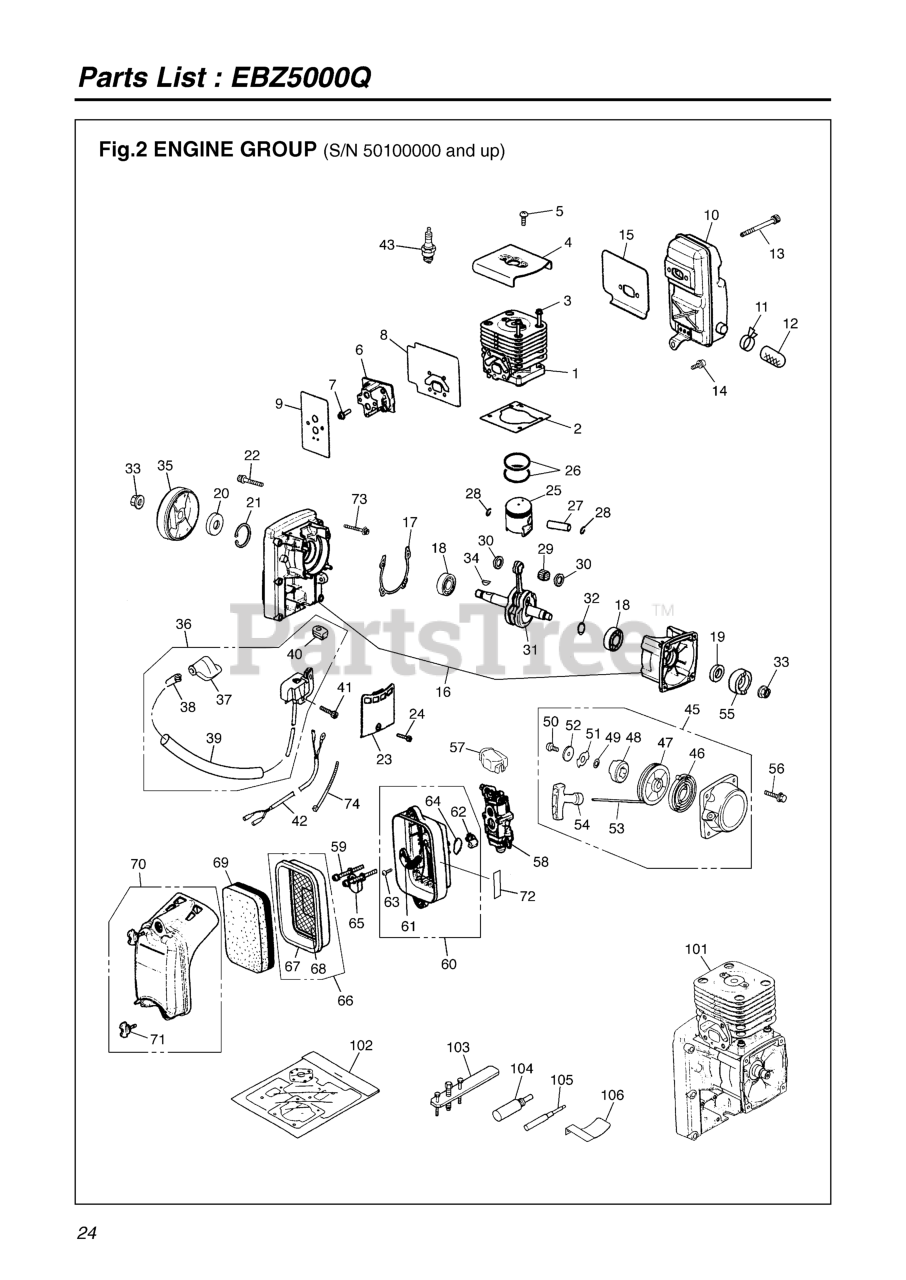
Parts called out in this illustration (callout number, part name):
1	CYLINDER
2	GASKET, BASE
3	BOLT
4	PLATE, CYLINDER
5	SCREW TORX
6	INSULATOR
7	BOLT
8	GASKET, INSU
9	GASKET, CARBURETOR
10	MUFFLER
11	ARRESTER
13	BOLT
14	BOLT
15	GASKET, MUFFLER
16	CRANKCASE-C
17	GASKET, CASE
18	BEARING (REPLACES 2810-21240)
19	SEAL, OIL 15 X 25 X 7
20	SEAL (REPLACES 1400-21220)
21	RING, SNAP, M35 X 1.5
22	BOLT
23	COVER
24	BOLT TORX
25	PISTON
26	RING, PISTON (REPLACES -41210)
27	PIN, PISTON
28	RING, SNAP
29	BEARING
30	WASHER (RPLS 1491-41510)
31	CRANKSHAFT COMP
32	SHIM (REPLACES 848-870-G000)
33	NUT, M10
34	KEY
35	ROTOR
36	COIL ASSY.
37	CAP
38	SPRING
39	TUBE
40	GROMMET
41	BOLT TORX
42	CORD-C
45	RECOIL ASSY
46	SPRING (RPLS -75220)
47	REEL
48	DOG
49	WASHER
50	SCREW
51	RETAINER (RPLS 1861-75161)
52	WASHER
53	ROPE
54	KNOB
55	PULLEY (RPLS -75210)
56	SCREW TORX
57	COVER
58	CARBURETOR (WYA 24A)
59	BOLT
60	BODY-A
61	PLATE,CHOKE
62	LEVER
63	SCREW
64	RING,O
65	PLATE
66	PACKING-C
67	PACKING
69	ELEMENT
70	COVER-A
71	KNOB
72	LABEL, CHOKE
73	BOLT
101	SHORT BLOCK
102	GASKET KIT
103	PULLER ASSY
104	STOPPER (TOOL)
105	PULLER, PISTON PIN
